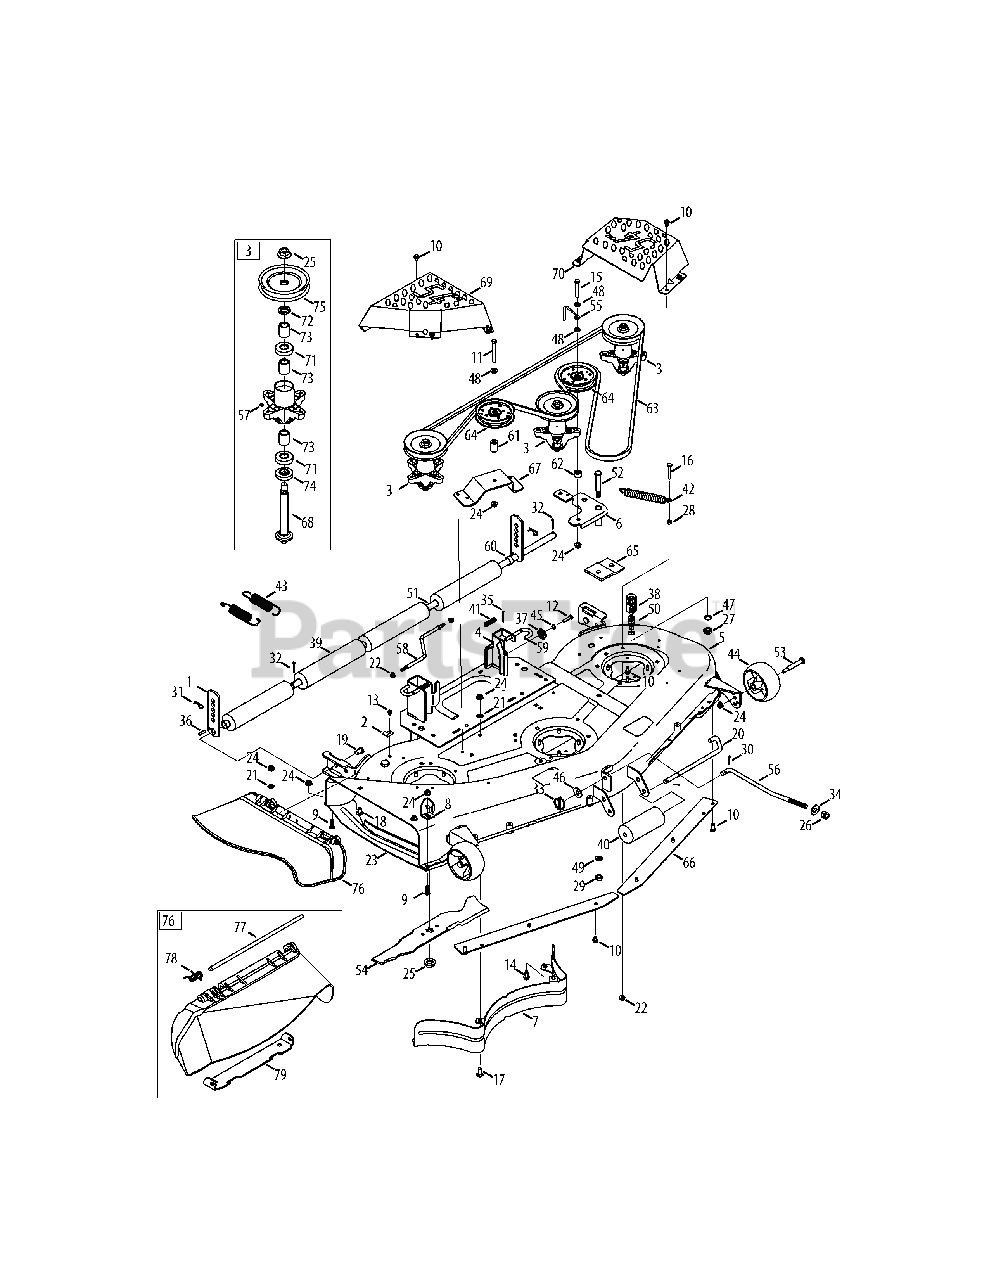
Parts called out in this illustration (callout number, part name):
2	Retainer Hook Bracket
3	Spindle Assembly
4	Deck Hanger Bracket Assembly
5	Deck Assembly
6	Idler Assembly
7	Inner Baffle
8	Deflector Chute Stop
9	Hex Screw, 3/8-16:1.00
10	Taptite Screw, 5/16-18:.750
11	Hex Screw, 3/8-16:3.00
12	Hex Screw, 5/16-18:1.25
13	Hex Screw, 1/4-20 x .500
14	Taptite Screw, 3/8-16:0.750
15	Hex Screw, 3/8-16:2.50
16	Hex Screw, 5/16-18:2.00
17	Carriage Bolt, 3/8-16:1.00
18	Carriage Bolt, 3/8-16:0.75
19	Clevis Pin, .50 DIA x .78 LG
20	Roller Pin, 1/2 DIA x 7.31 LG
21	Push Nut, 3/8
22	Flangelock Nut, 5/16-18
23	Finger Guard
24	Flangelock Nut, 3/8-16
25	Flange Nut, 5/8-18
26	Flexlock Nut, 1/2-13
27	Hex Nut, M16-1.5 DIN 936
28	Hex Nut, 5/16-18
29	Hexlock Nut, Counterlock, 1/2-13
30	Cotter Pin, 3/32:1.0
31	Click Pin, .092 x 1.64 LG
32	Cotter Pin, 5/32:1.25
33	Lynch Pin, .1875
34	Washer, .630 x 1.25 x .180
35	Cotter Pin, 1/8 x 1.25
36	Spring Pin, 1/4 DIA x 1.00 LG
37	Deck Gear
38	Water Nozzle Adaptor
39	Deck Roller
40	Front Roller
41	Compression Spring, .535 OD x 1.751 LG
42	Extension Spring, .85 OD x 5.915 LG
43	Extension Spring, 1.15 OD x 5.99 LG
44	Deck Wheel
45	Lock Washer, 5/16
46	Flat Washer, .531 x 1.25 x .100
47	Lock Washer, 5/8
48	Flat Washer, .406 x .875 x .059
49	Lock Washer, 1/2
50	Deck Water Nozzle
51	Shaft, .750 x .47.12
52	Shield Screw, .625 x 2.50:1/2-13
53	Shoulder Bolt, .496 x 2.50:3/8-16
55	Belt Keeper Rod
56	Deck Lift Rod
57	Lube Fitting
58	Deck Sway Rod
59	Deck Release Handle Rod
60	Spacer, .82 ID x 1.00 OD x .53
61	Spacer, .380 x .900 x 1.313
62	Spacer, .385 ID x .88 x .64
63	V Belt
64	Idler Pulley, 4.25"DIA
65	Pulley Stabilizer Bracket
66	Deck Skirt
67	Stationary Idler Bracket
68	Spindle Shaft, 6.95 LG
69	RH Spindle Cover
70	LH Spindle Cover
71	Ball Bearing, .787 ID x 1.85 OD x .551
72	Spacer, .790 ID x 1.25 OD x .175
73	Spacer, .80 x 1.10 x 1.322 LG
74	Spacer, .79 x 1.82 x .55 LG
75	Deck Pulley
76	Chute Assembly
77	Hinge Pin
78	Torsion Spring, .44 ID x 2.0
79	Chute Bracket
